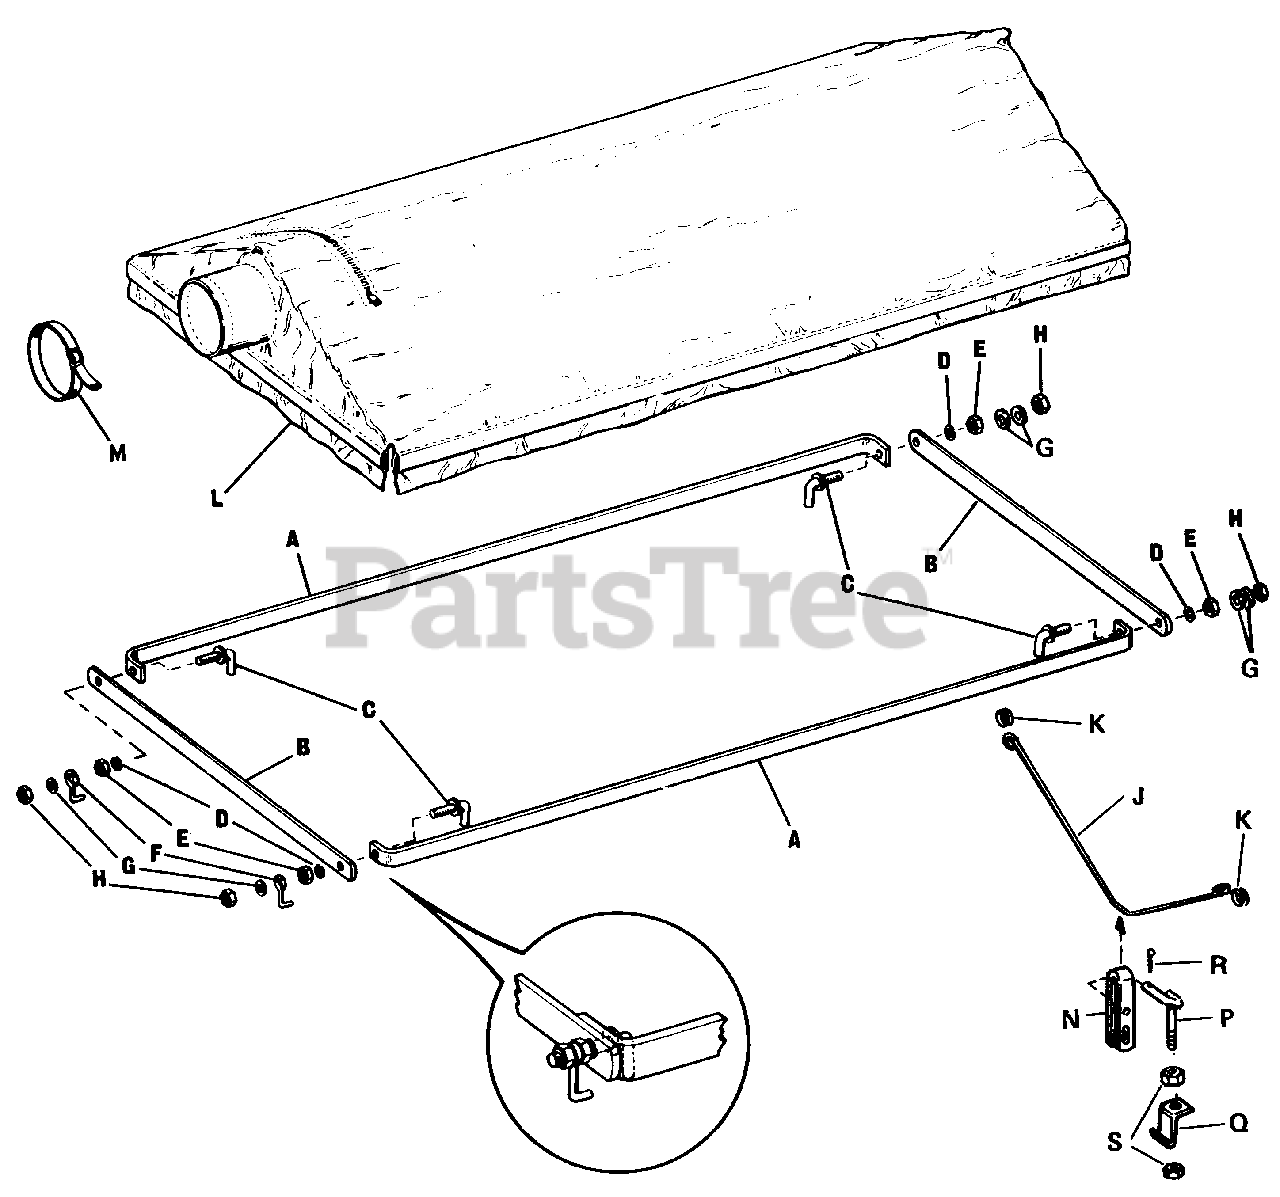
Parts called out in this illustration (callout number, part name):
A	Side Member-Frame
B	End Bracket-Frame
C	Stud Ass'y-Special
D	Lock Washer, 5/16"
E	Hex Nut Full 5/16"-18NC
G	Washer-Plain 5/16
H	Hex Nut Full Lock, 5/16"-18NC
K	Repair Link
L	Cover W/Hose Strap
M	Hose Strap (Service Only)
P	Latch Rod
R	Cotter Pin, 1/8" x 1"
S	Hex Nut Full Lock, 3/8"-16
